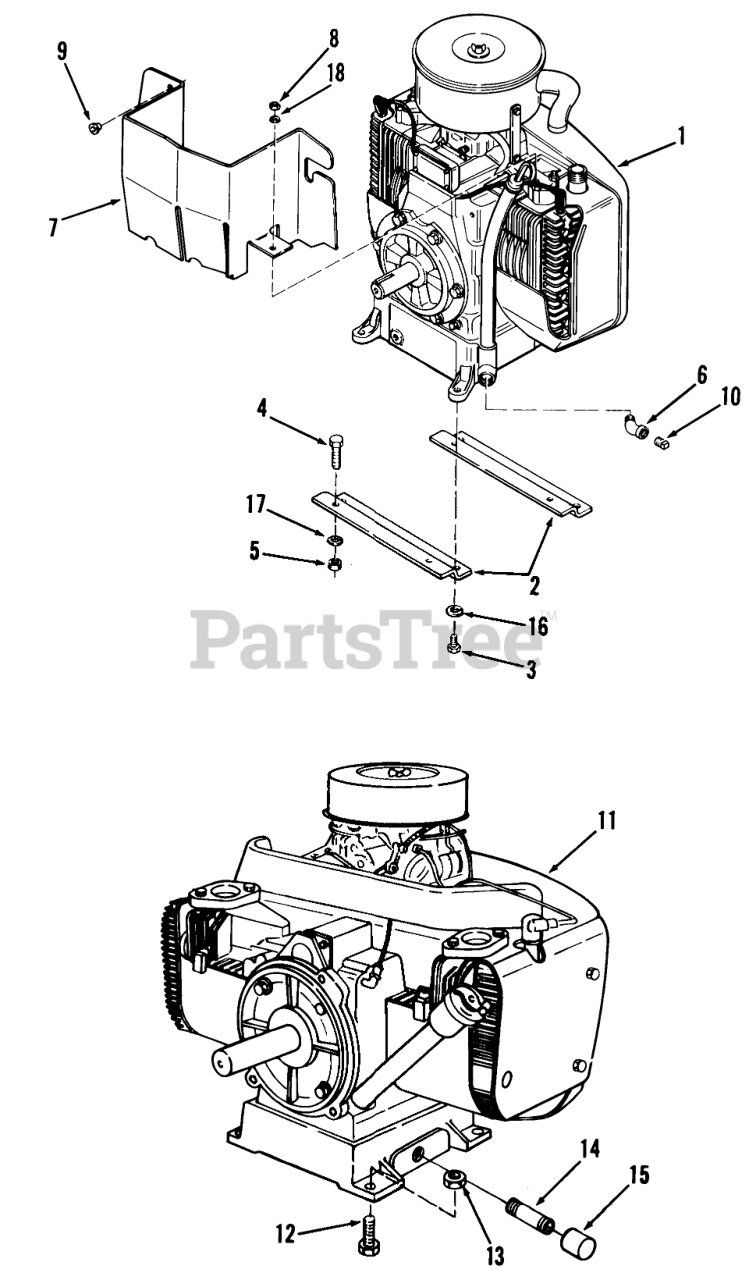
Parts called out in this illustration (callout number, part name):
1	Engine-16 HP (Onan Model B43M-GA016 Spec.3602A)
11	Engine 19.9 HP Kohler
14	Nipple 3/4 Pipe X2
17	WASHER 5/16 SAE
